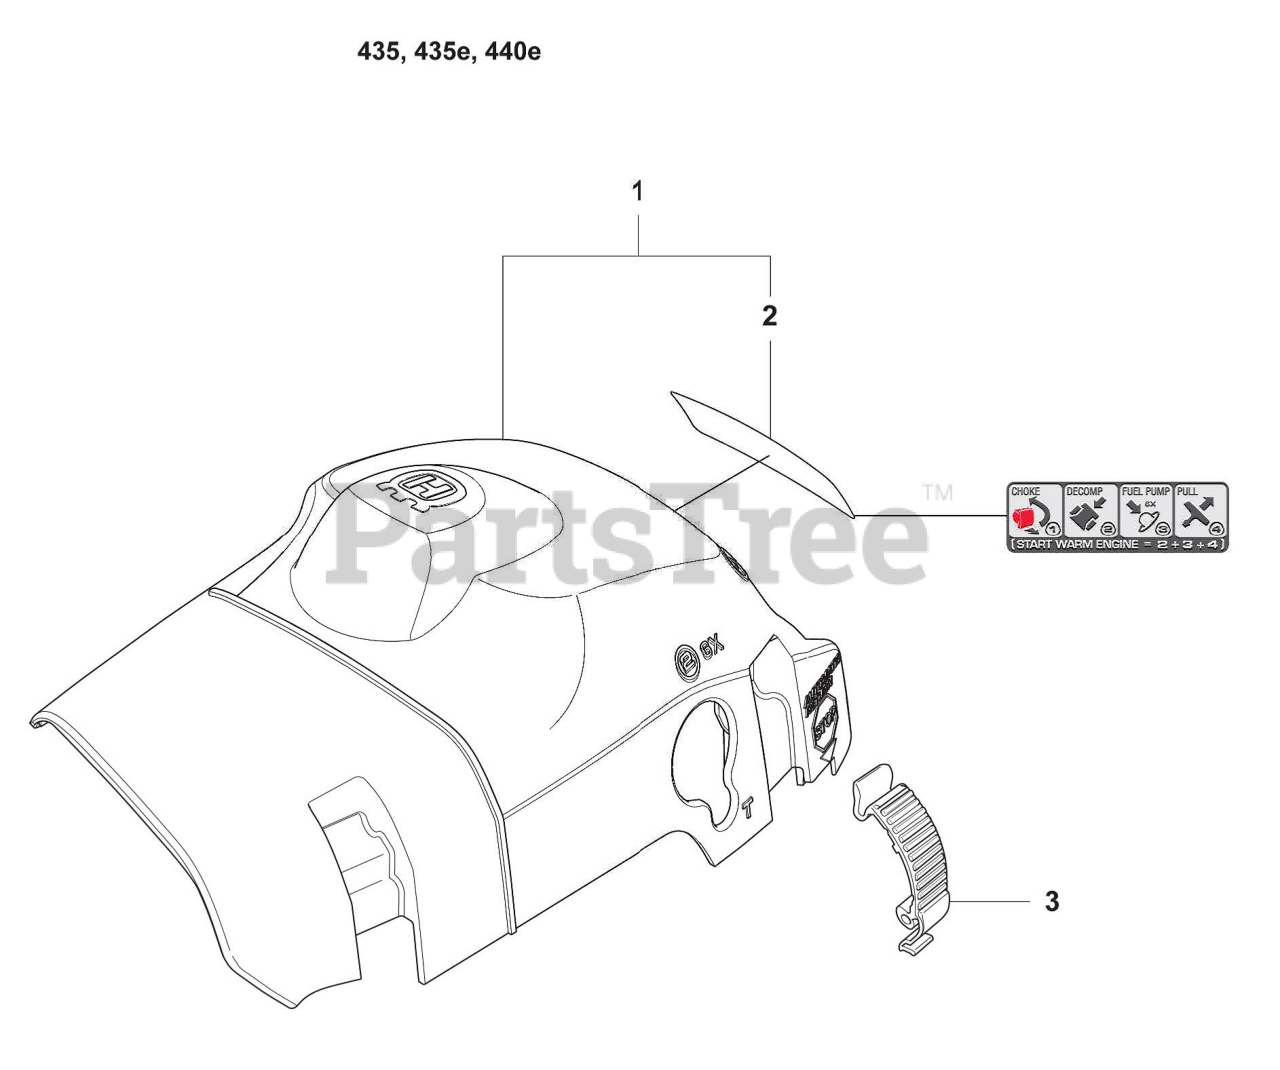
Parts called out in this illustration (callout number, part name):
1	Cylinder Cover Assembly
2	Label
3	Top Cover Buckle Clip, Orange
